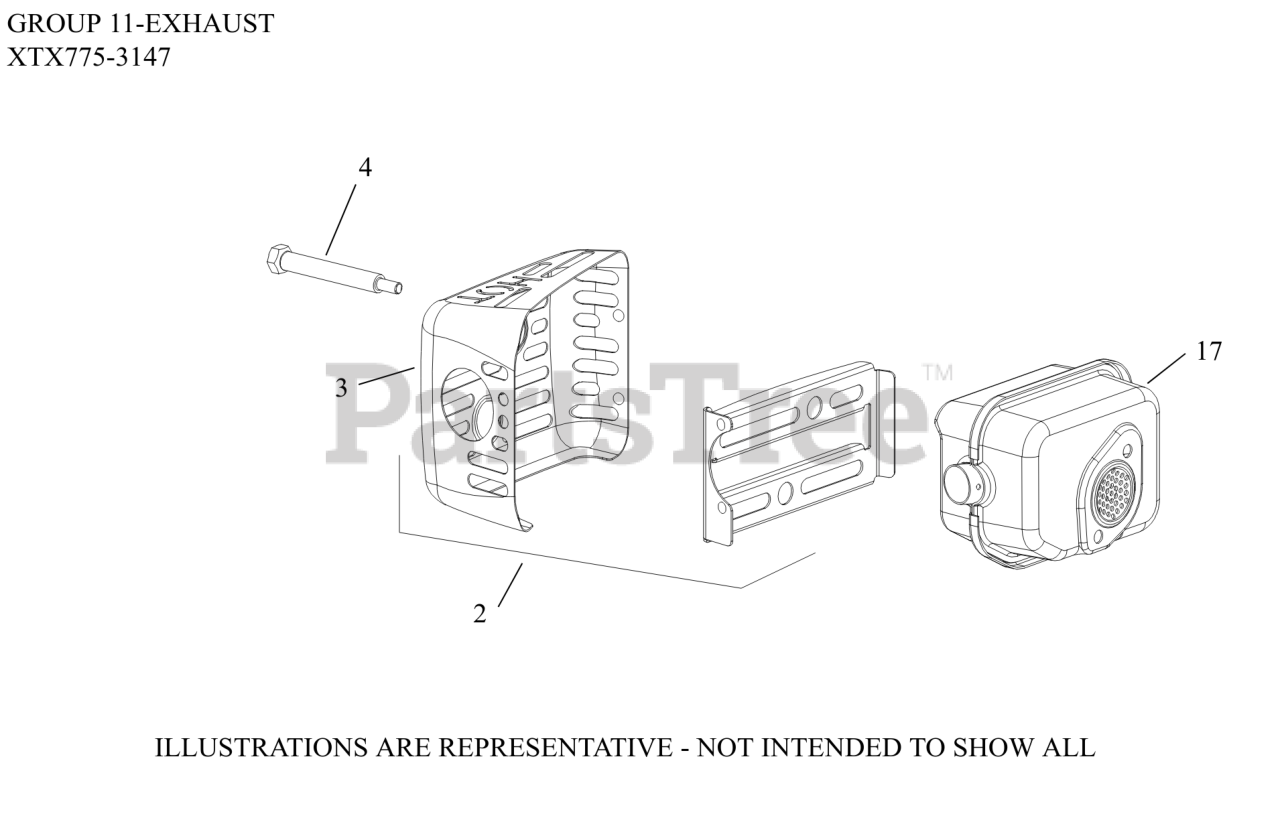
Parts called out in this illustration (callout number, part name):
2	GUARD, MUFFLER ASSEMBLY
3	GUARD, MUFFLER - DISCONTINUED
4	SCREW, SHOULDER
17	MUFFLER, ASSEMBLY
